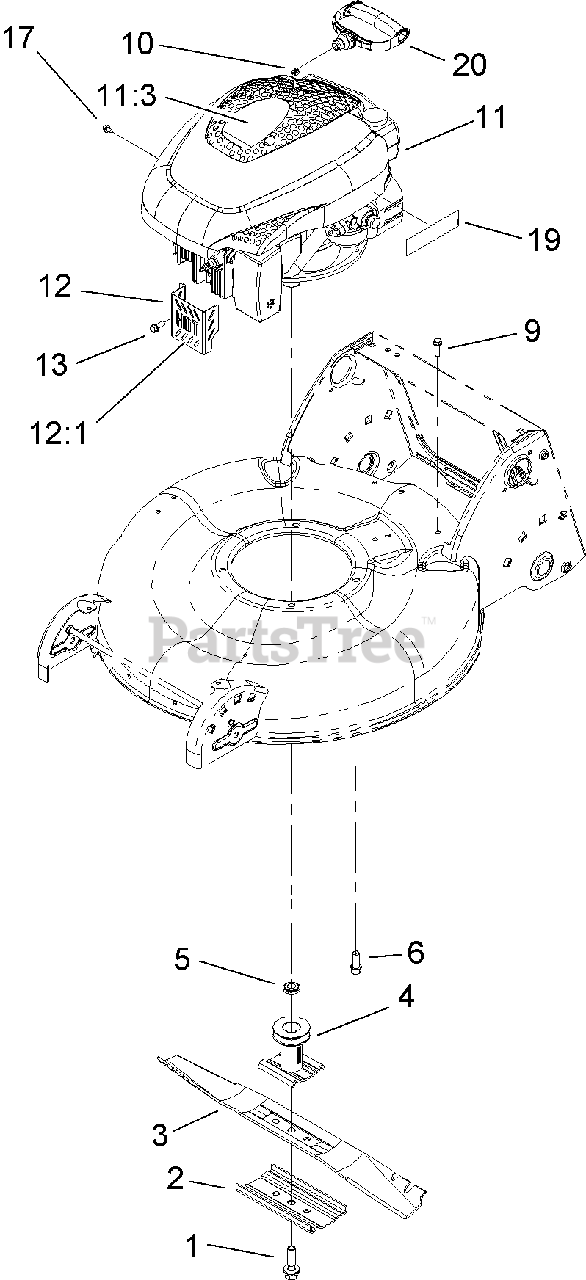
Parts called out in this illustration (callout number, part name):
1	BOLT-BLADE
2	SUPPORT-BLADE
3	BLADE-21 INCH
4	BLADE DRIVER ASM
5	Spacer-Driver
6	SCREW
9	SCREW-HWH
10	STOP-ROPE
11:3	DECAL-RECOIL
12	MUFFLER GUARD ASM
12:1	DECAL-SURFACE, HOT
13	SCREW-HWH
17	SCREW-HWH
19	DECAL-PRIMER
20	HANDLE-RECOIL
